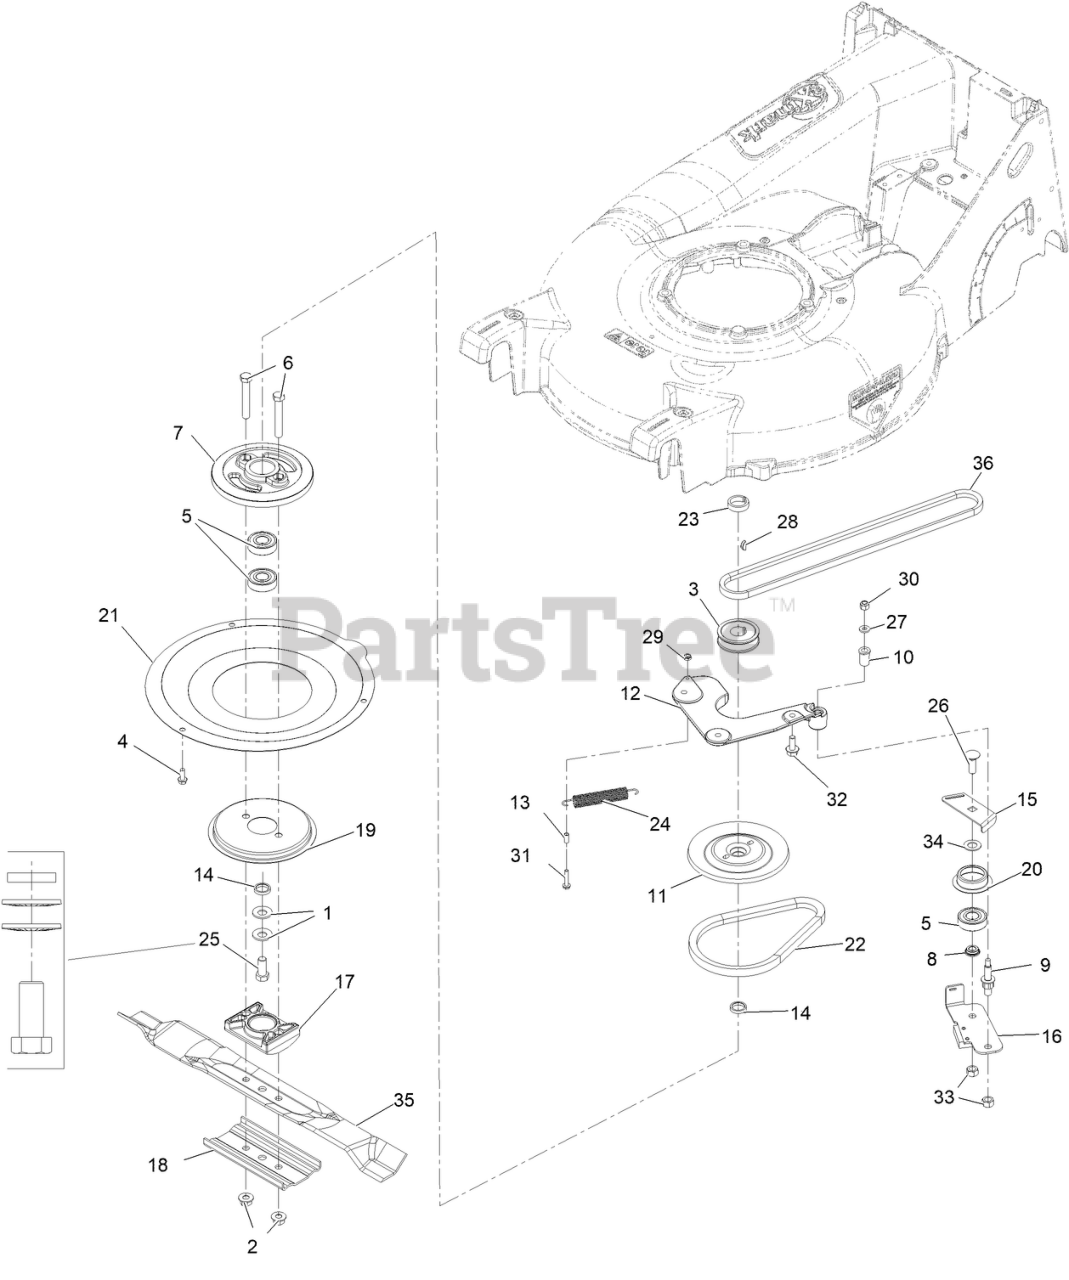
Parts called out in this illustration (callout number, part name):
1	WASHER-SPRING
2	NUT-FLANGE, LOCK
3	PULLEY-DRIVER
4	SCREW-HWH
5	BEARING-BALL
6	SCREW-HH
8	SPACER-BEARING
9	BOLT-SHOULDER
10	BUSHING
11	PULLEY-DRIVER, UPPER
12	PLATE-MOUNTING, BBC
13	SPACER-BBC
14	SPACER-PLATE, BBC
15	Plate-Guide
16	PLATE-BRAKE
17	SUPPORT-BLADE
18	SUPPORT-BLADE
20	RETAINER-BELT
21	COVER-BBC
22	BELT
23	SPACER-PULLEY
24	SPRING-EXTENSION
25	SCREW-HH
26	Bolt-Carriage 3/8-16 X 1 1/4
27	WASHER-FLAT
28	KEY-WOODRUFF
29	NUT-LOCK, NI
30	NUT-LOCK, NI
31	SCREW-TAP
32	SCREW-HHF
33	NUT-HEX
34	SPACER
35	Blade-Mulch, 20.5
35	Blade-21In
35	Blade - Medium Lift, 20.5
36	BELT,3L P21 DRIVE
